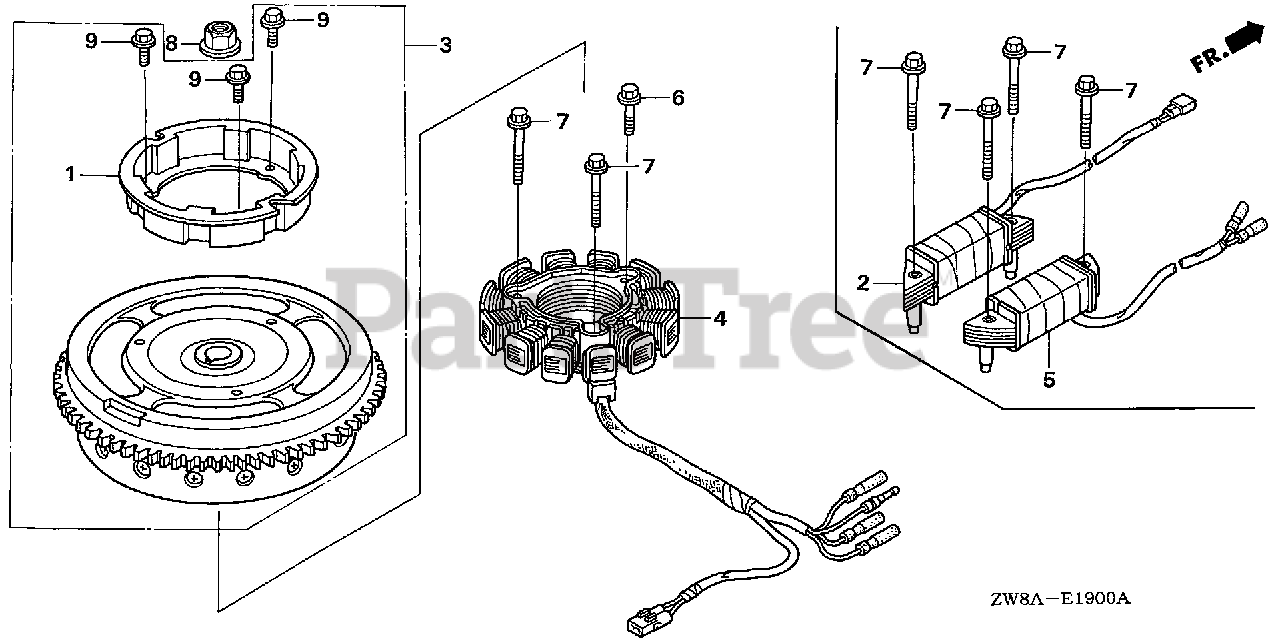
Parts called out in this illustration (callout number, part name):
1	PULLEY, STARTER
3	FLYWHEEL *TBLACK* (SELF STARTER) (BLACK)
4	COIL ASSY., CHARGE (12A)
6	BOLT, FLANGE (6X36) (CT200)
7	BOLT, FLANGE (6X52) (CT200)
8	NUT, SPECIAL (14MM)
9	BOLT, FLANGE (6X10)
